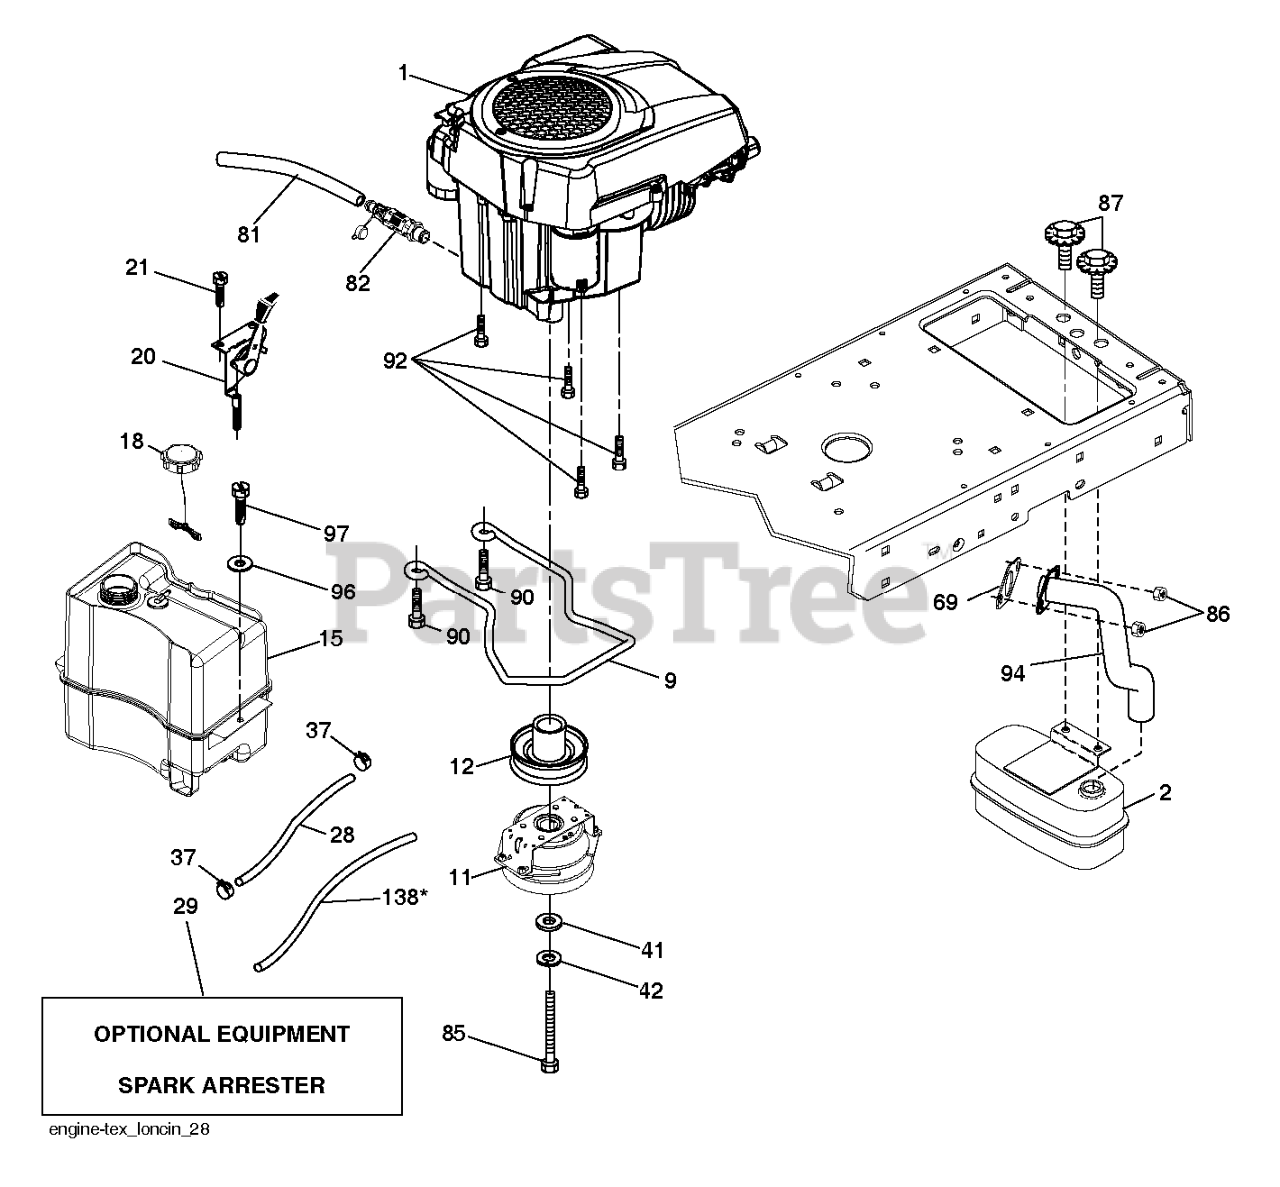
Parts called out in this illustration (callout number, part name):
1	ENGINES
2	MUFFLER.ASM.SINGLE
9	KEEPER.BELT.ENG.4.25"2.BLT.431
11	CLUTCH.OGURA.4.4PD.GT1.5-EH13V
12	PULLEY.ENGINE.TUFFTORQ
15	FUEL.TANK.ASM.NON-EPA
15	Tanks
18	CAP ASM.FUEL.2.25"FR.
20	CONTROL.TH/CK.C.
28	LINE.FUEL.20
29	KIT.SPARK ARRESTOR 794945 B&S
37	HOSE CLAMP
69	GASKET GASKET.EXHAUST. LONCIN
81	TUBE, DRAIN OIL ASM.
82	VALUE.OIL.DRAIN
85	CLUTCH BOLT7/16-20X3.5 GR524HR
86	NUT.HEX.FLANGE.TOPLOCK
87	BOLT.5/16-18UNCX3/4 W/SEMS.BLK
90	SCREW 3/8-16X1
92	SCREW 3/8-16X1
94	TUBE TUBE.EXHAUST.LONCIN 608.T
97	SCREW HEXWSHR 1/4-20X3/4
